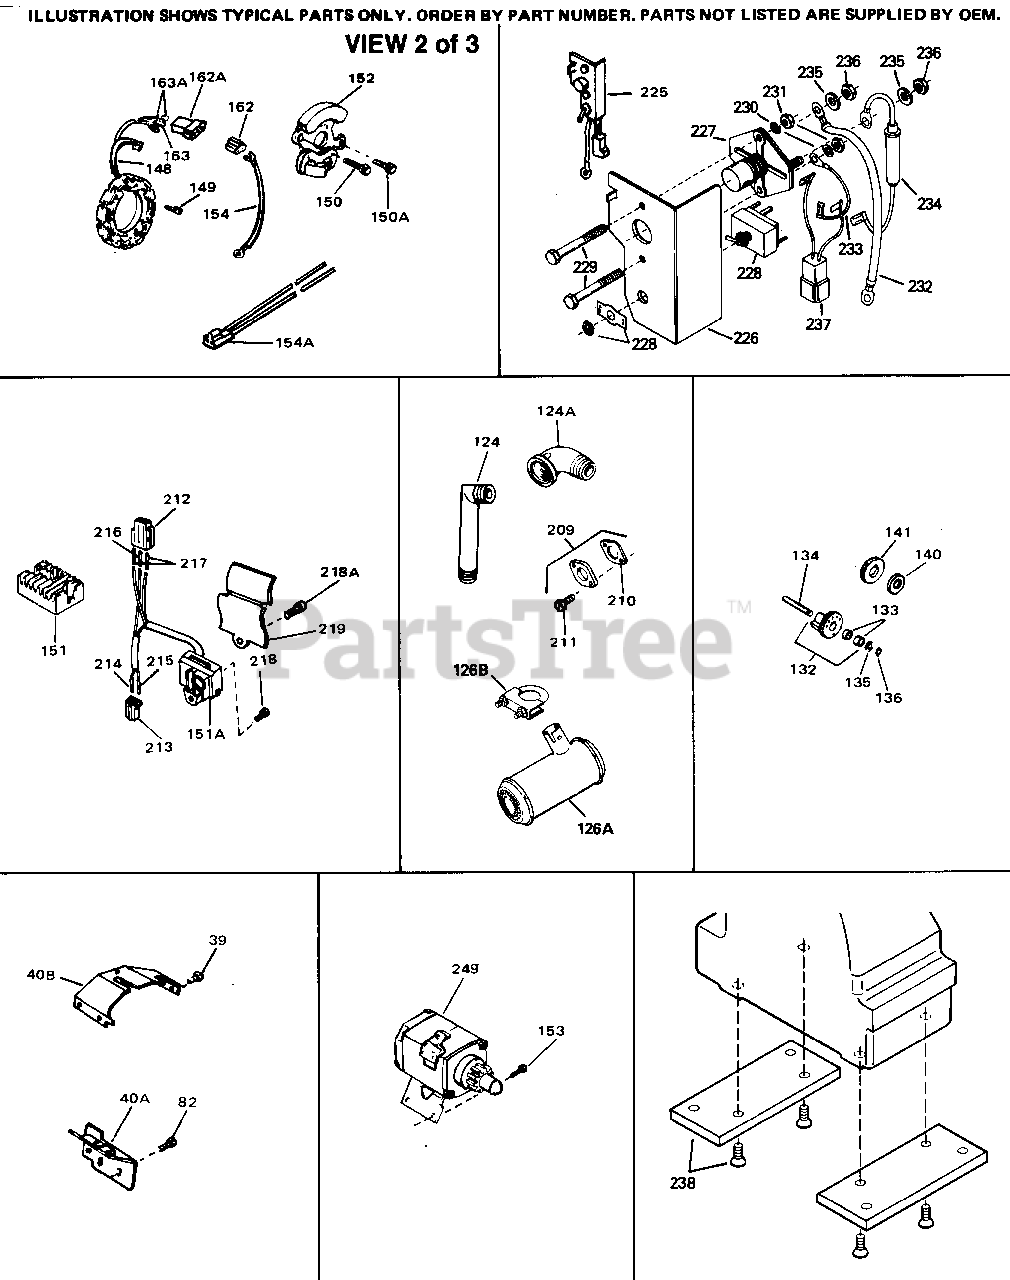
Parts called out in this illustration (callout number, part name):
39	Screw, 10-16 x 3/8"
126A	Muffler (Incl. 126B)
141	Gear, Counterbalance weight (Straight teeth) (For replacement see Ref. 132 . Order correct kit for your enginemo del number.)
147	Screw, 5/16-18 x 7/8"
153	Screw,5/16-18 x 11/16" Use w/33835 st r.motor
153	Screw, 5/16-18 x 7/8" Use w/32817 str .motor
209	Ech.Adapter Kit (Incl. 210 & 211) As required
210	Gasket, Exhaust (Use as required)
211	Screw, 5/16-18 x 3/4"
238	Adapter Plate Kit (Optional) NOTE: I f you are having mounting problems in using a HH100 thru0H180 inplace of a large frame competitivebrand, we wou ld like to call your attention to 730 212 adapter plate kit. The kit conve rts the bottom mounting
